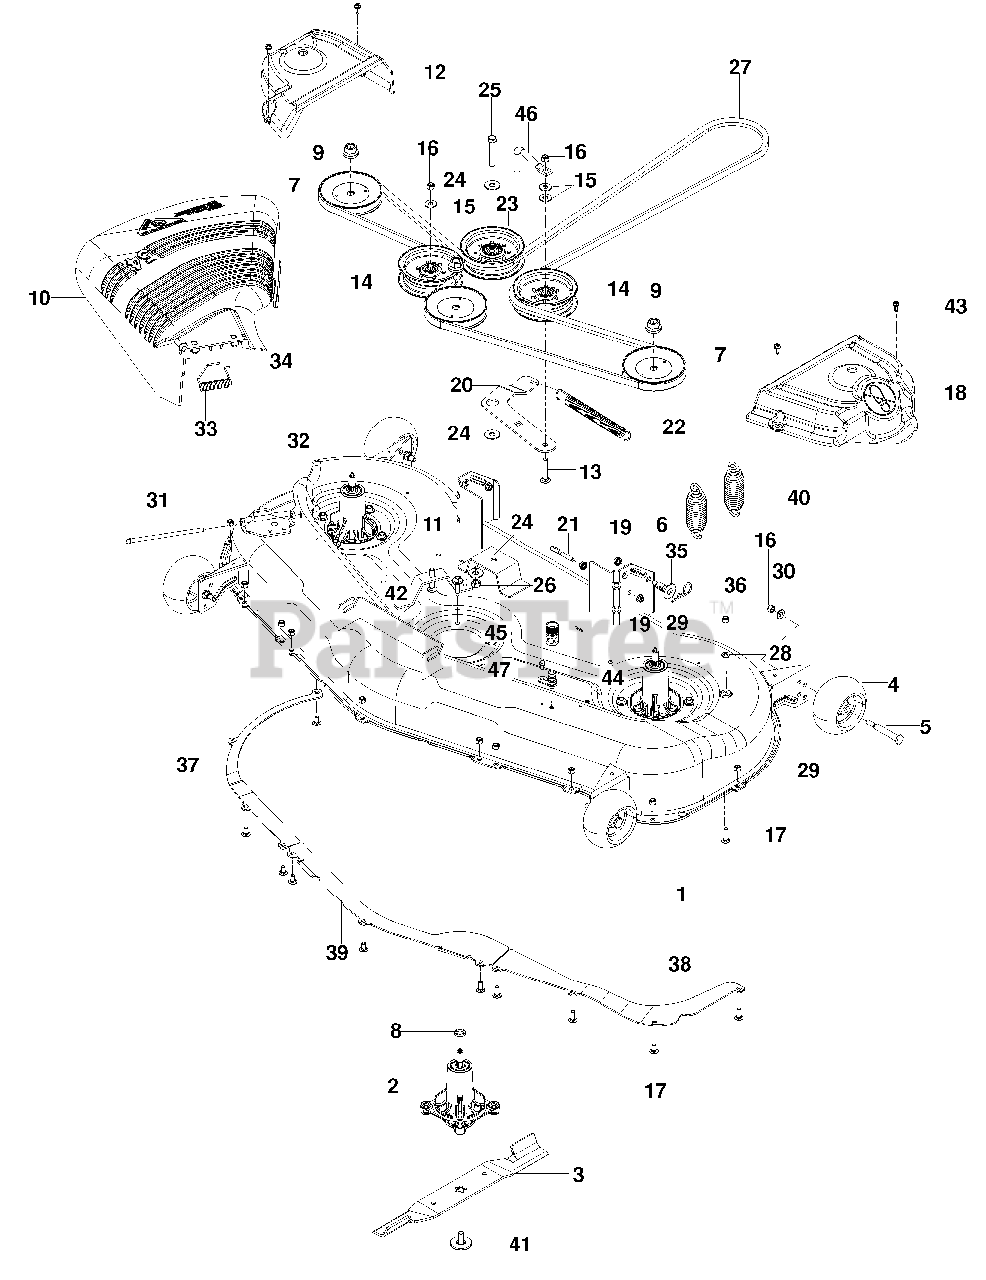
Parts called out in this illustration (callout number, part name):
1	DECK w/ SAFETY DECALS
2	HOUSING, CUTTER
3	BLADE, BAGGING
4	WHEEL, GAUGE
5	BOLT 3/8-16 SHOULDER
6	STUD w/ ANTI-ROTATE
7	PULLEY
8	WASHER/SPACER
9	NUT 9/16 TOP CNTRLK
10	DEFLECTOR, 54"
11	RHSNB 3/8-16 x 2
12	BELT SHIELD, RT
13	BOLT 3/8-16 x 2 1/2 CARRIAGE
14	PULLEY, IDLER
15	WASHER 3/8 FLT STD
16	NUT 3/8-16 HEX NYLOC
17	RHSNB 5/16-18 x 3/4
18	BELT SHIELD, LT
19	NUT 5/16-18 FLANGE NYLOC
20	ARM, IDLER
21	EYE BOLT 5/16 x 3 1/2
22	SPRING, DECK BELT
23	PULLEY, IDLER
24	WASHER 7/16 FLT
25	HCS 7/16-14 x 2 1/2
26	NUT 7/16-14 HEX
28	WASHER 5/16 SAE FLT
29	NUT 5/16-18 HEX NYLOC
30	WASHER 3/8 SAE FLT
31	ROD, HINGE
32	PUSHNUT
33	SPRING, TORSION
34	CAP, SLEEVE
35	WASHER 1/2 FLT
36	HAIRPIN #4
37	BAFFLE, RIGHT 54
38	BAFFLE, LEFT 54"
39	BAFFLE, CENTER 54"
41	BOLT WASHER ASSY
42	SCREW 5/16-18 x WSHER HD
43	SCREW 1/4-20 x 5/8 THDROLL
44	PORT, WASHOUT
45	COUPLING, QUICK CONN
46	BELT KEEPER
47	BOLT 1/4-20 x 1/2 HWST
